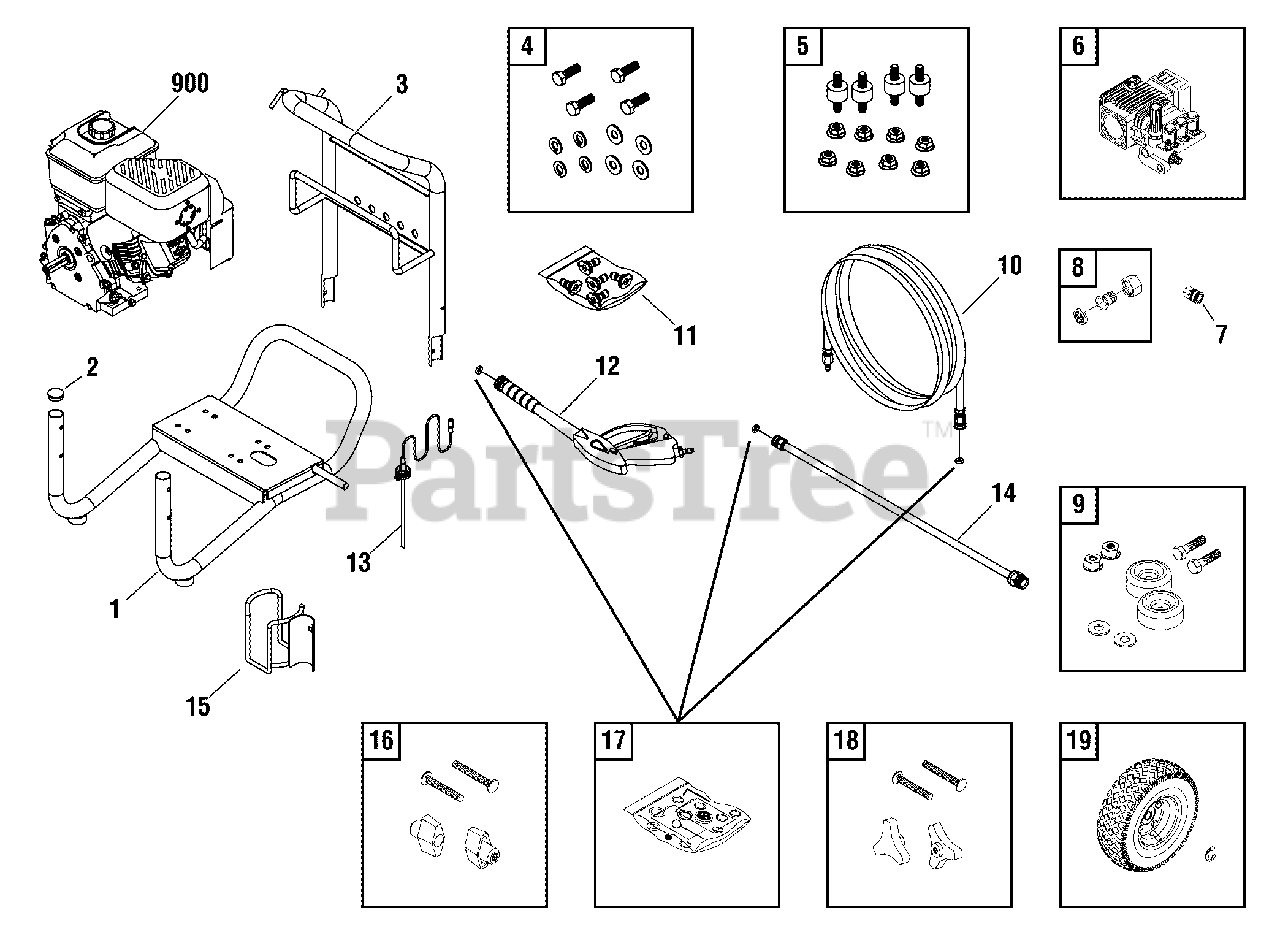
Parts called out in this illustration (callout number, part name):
4	KIT-HARDWARE PUMP MOUNTING
5	KIT-VIBRATION MOUNT
7	ADAPTER
8	ADAPTER-GARDEN HOSE
9	MOUNT-VIBRATION
14	EXTENSION-QC
16	KIT-HARDWARE HANDLE
18	KIT-HARDWARE HANDLE
